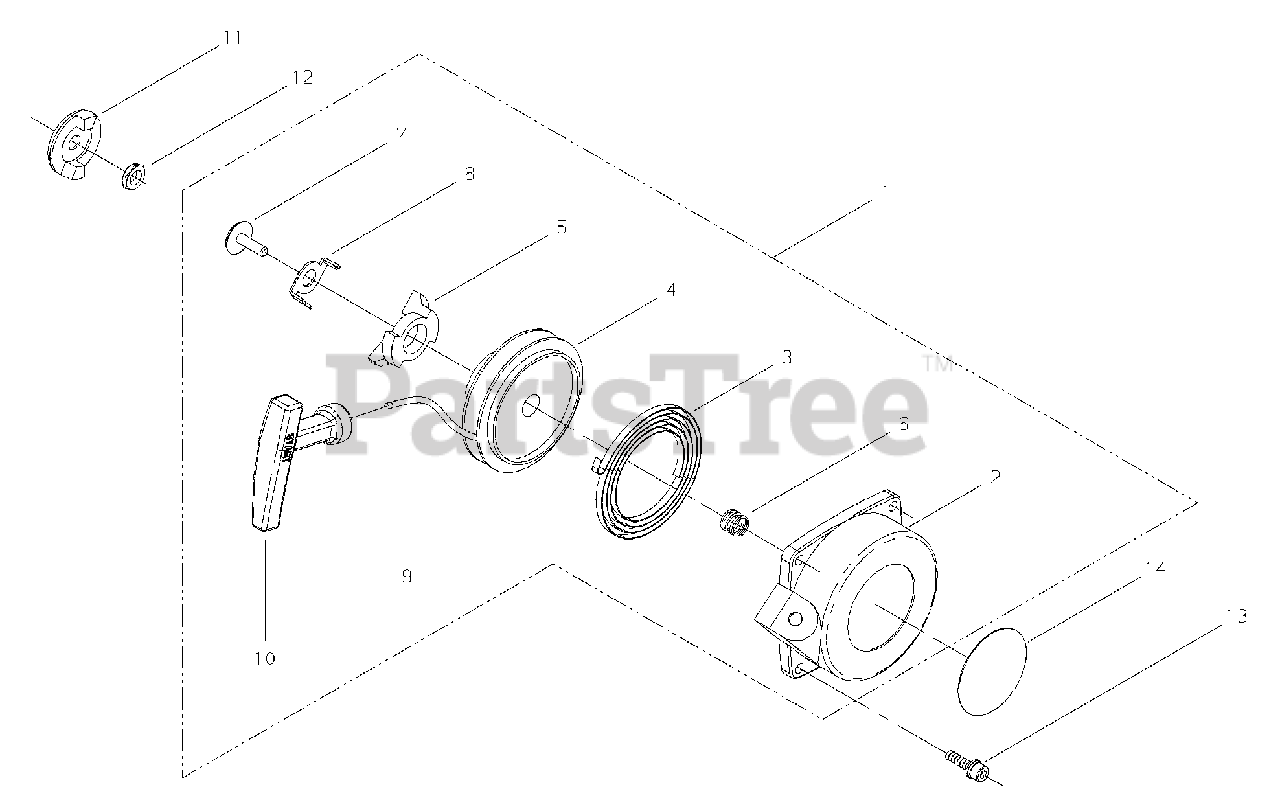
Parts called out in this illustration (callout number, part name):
1	STARTER ASSY
2	CASE, RECOIL STARTER
3	SPRING, RECOIL
4	REEL, ROPE
5	PAWL, STARTER
6	SPRING, PAWL
7	SCREW
8	RETAINER
9	ROPE, STARTER
10	GRIP, STARTER
11	PULLEY, STARTER
12	NUT M8×1
13	BOLT M5×20
14	LABEL, RECOIL C4
